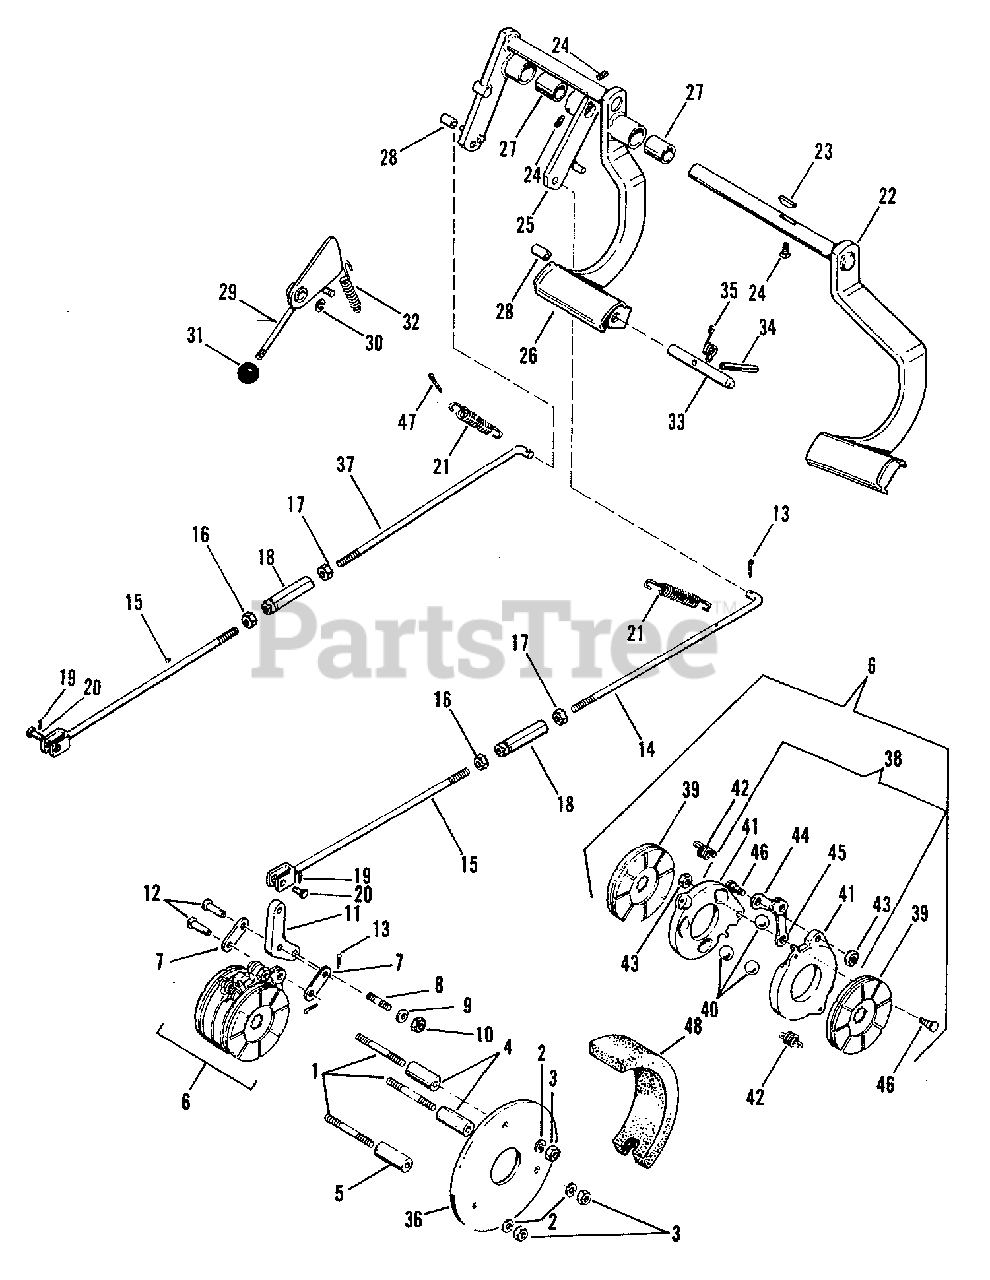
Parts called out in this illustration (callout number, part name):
2	LOCKWASHER, 3/8"
3	NUT, Hex, 3/8-16
6	BRAKE ASSEMBLY
7	PLATE, Link
9	WASHER, Plain, 5/16"
10	NUT, Hex, Full, Lock, 3/8"-16
11	LEVER, Brake
13	PIN, cotter, 3/32" x 3/4" Lg.
14	ROD, Front Brake, R.H.
15	REAR BRAKE ROD ASSEMBLY
16	NUT, Hex, Jam, 3/8"-24 R.H.
17	NUT, Hex, Jam, 3/8"-24 L.H.
18	TURNBUCKLE
19	PIN, Cotter
21	SPRING
22	BRAKE LEVER ASSEMBLY, R.H.
24	SCREW, Set, 5/16"-18 x 3/8" Lg.
25	BRAKE ROD ANCHOR ASSEMBLY
26	BRAKE LEVER ASSEMBLY, L.H.
27	SLEEVE, Bearing
28	STOP, Rubber
29	CAM ASSEMBLY
30	RING, Retaining
33	PIN, Pedal Lock
34	PIN, Roll
36	PLATE, Shim
37	ROD, Front Brake, L.H.
38	ACTUATING DISC ASSEMBLY
39	MIDDLE DISC ASSEMBLY
41	DISC, Actuating
43	NUT, Hex, Jam
44	LINK ASSEMBLY, Yoke
45	LINK, Actuating
47	PIN, Cotter, 5/32 x 1
